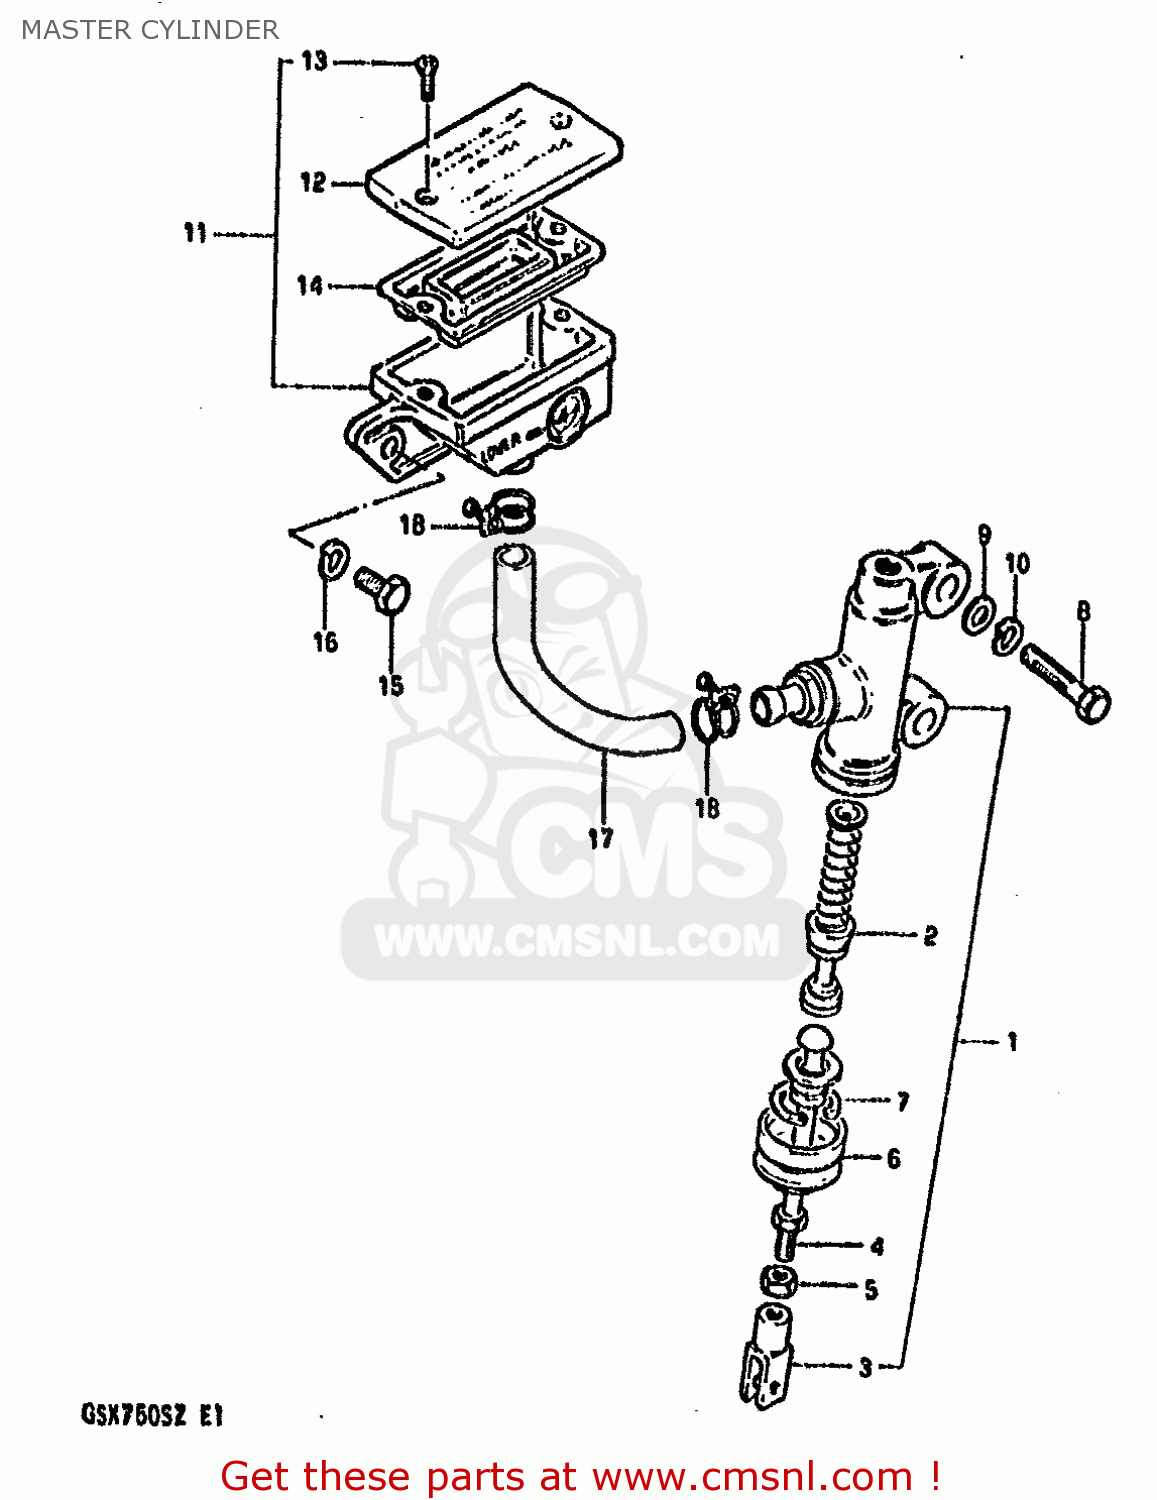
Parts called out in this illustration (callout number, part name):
1	CYLINDER ASSEMBLY,REAR MASTER
2	PISTON/CUP SET
3	YOKE
4	LOD,PUSH
5	NUT,MASTER CYLINDER
6	BOOT
7	CIRCLIP
8	BOLT (8X30)
9	WASHER
10	LOCK WASHER
11	RESERVOIR TANK ASSY
12	CAP
13	SCREW
14	15
15	BOLT, UPPER
16	LOCK WASHER
17	HOSE,RESERVOIR TANK
18	CLAMP
